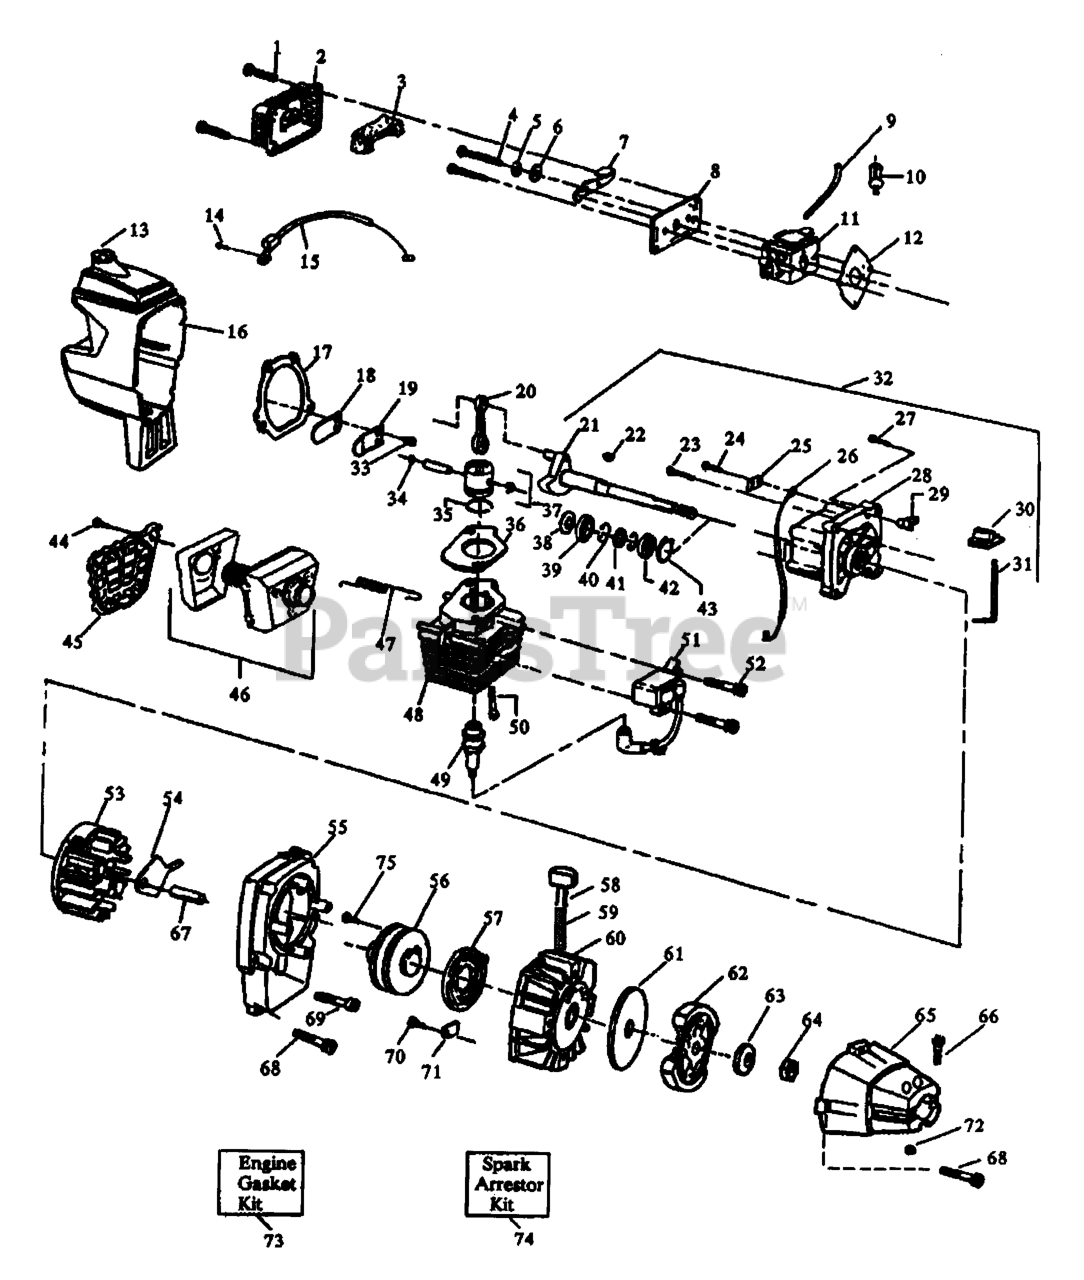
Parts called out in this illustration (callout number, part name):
1	SCREW-10-24 X 13/16
2	COVER-FILTER
3	AIR FILTER
4	SCREW
5	SPACER-CHOKE
7	SHUTTER-CHOKE
8	PLATE-AIR FILTER MTG.
9	HOSE. FUEL
10	ASSY-FUEL PICK-UP
11	CARBURETOR (WA-199)
12	GASKET-CARBURETOR
14	SCREW 8-16 X 9/16 (PLAS
15	ASSY-THROTTLE CABLE (SR
16	Shroud & Tank Ass'y.
17	GASKET-C'CASE/SHROUD
18	VALVE-REED
20	ASS'Y-CONNECTING ROD
21	ASSY-CRANKSHAFT
22	KEY-FLYWHEEL
23	SCREW-10-24 X 1" (TAP.)
24	SCREW 6-19X5/8 PLAS.PAN
25	INSULATOR-KILL SWITCH
26	LEAD WIRE-KILL SWITCH
27	SCREW 1/4-20 X 7/8 (TAP
28	Crankcase Ass'y.
29	KILL SWITCH RAMP
30	BUTTON-KILL SWITCH
31	SPRING-KILL SWITCH
32	ASSY-C'CASE & C'SHAFT
33	SCREW-6-19X5/16PLAST PA
34	WRIST PIN RET.
35	RING-PISTON (26.2CC)
36	GASKET-CYLINDER
37	Piston Kit
38	SPACER-BEARING
39	Inner Bearing
40	RING-RETAINING
41	SEAL-CRANKSHAFT
42	BEARING-R8 (OUTER)
43	RING-RETAINING (SHAFT)
44	SCREW-10-16X9/16SLTD.PH
45	GUARD-MUFFLER
46	KIT-MUFFLER ASS'Y
47	SPRING
48	CYLINDER (26CC) (SERVIC
49	Spark Plug
50	SCREW-1/4-20 X 13/16
51	MODULE-IGNITION
52	SCREW 8-32 X 1-9/32
53	ASSY-FLYWHEEL
54	COUNTERWEIGHT FLYWL 26RLC
55	HOUSING-FAN (ORANGE)
56	KIT-STARTER PULLEY
57	SPRING-STARTER
58	HANDLE-STARTER
60	ASSY-PULLEY HSG (ORANGE
61	WASHER-CLUTCH
62	KIT-CLUTCH ASS'Y
63	WASHER-BELLEVILLE
65	ASSY-CLUTCH HSG (ORANGE
66	SCREW-10-24 X 1-3/8 (UN
67	SPACER-CLUTCH
69	SCREW-10-24X1-3/8-TAPTI
70	SCREW-10-16 X 1/2 HI-LO
72	LOCKNUT-HEX 10-24
73	KIT-GASKET
74	Spark Arrestor Kit
75	SCREW-6-19X9/32 PAN/SEM
